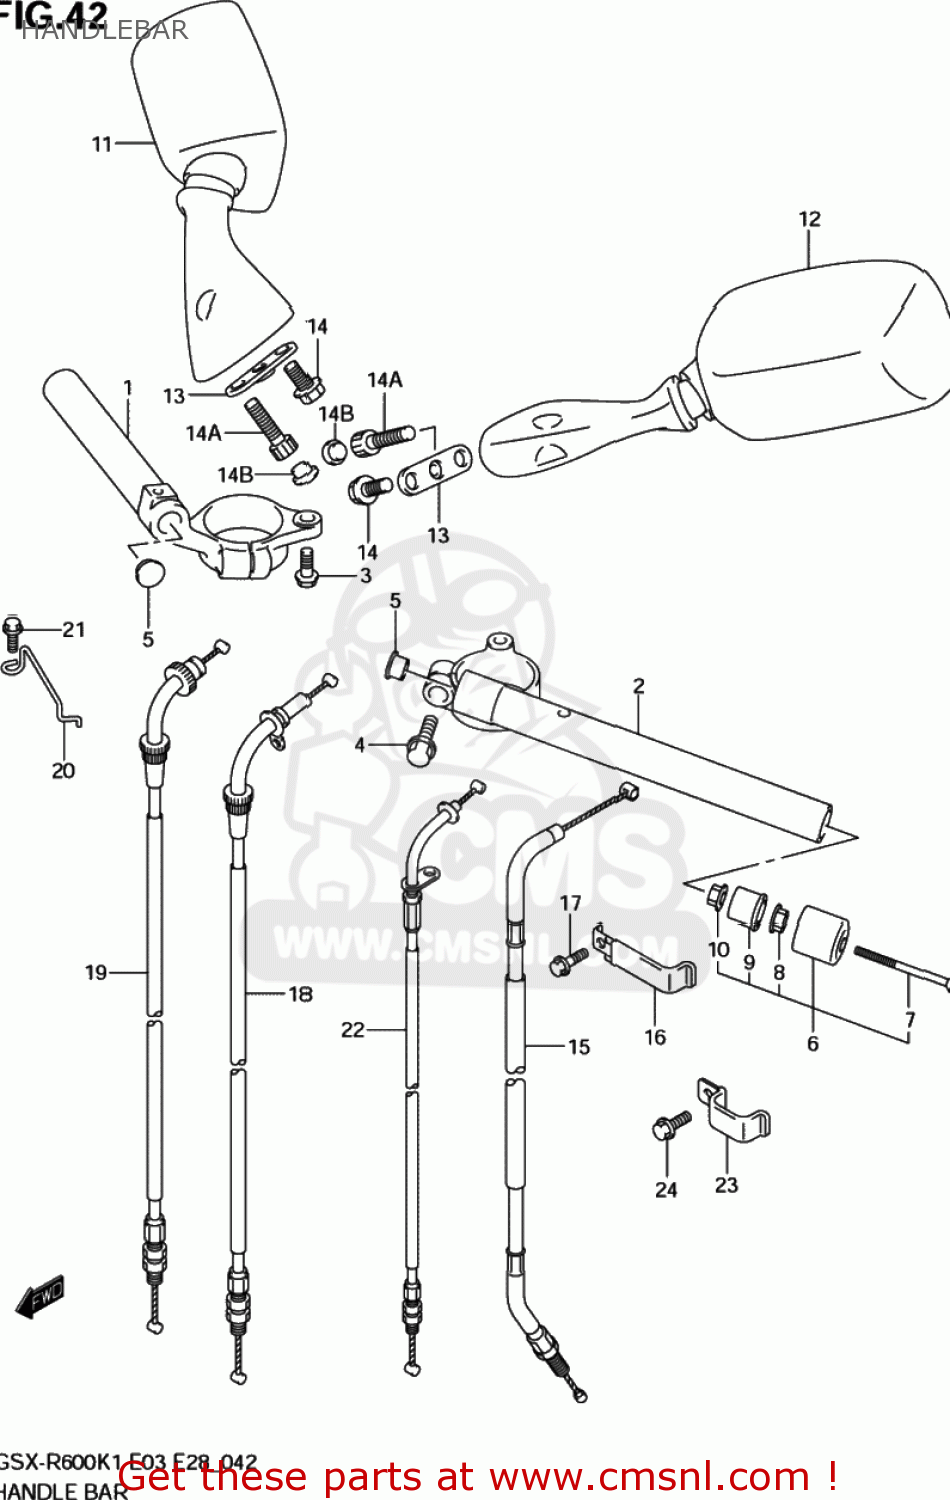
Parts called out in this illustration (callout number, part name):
1	HANDLEBAR,R
2	HANDLEBAR,L
3	BOLT
4	BOLT,HANDLEBAR
5	PLUG(OD:17)
6	BALANCER,HANDLEBAR
7	SCREW
8	NUT
9	EXPANDER,HANDLE BALANCER
10	NUT
11	MIRROR ASSY,RR VIEW,R
12	MIRROR ASSY,RR VIEW,L
13	CUSHION,RR VIEW MIRRORR
14	BOLT,G/S SWITC
14A	BOLT
14B	CAP(OD:10)
15	CABLE ASSY,CLUTCH
16	CLAMP,WIRING HARNESS
17	BOLT
18	CABLE ASSY,THROTTLE
19	CABLE ASSY,THROTTLE NO.2
20	GUIDE, CABLE
21	BOLT
22	CABLE,STARTER
23	CLAMP
24	BOLT
